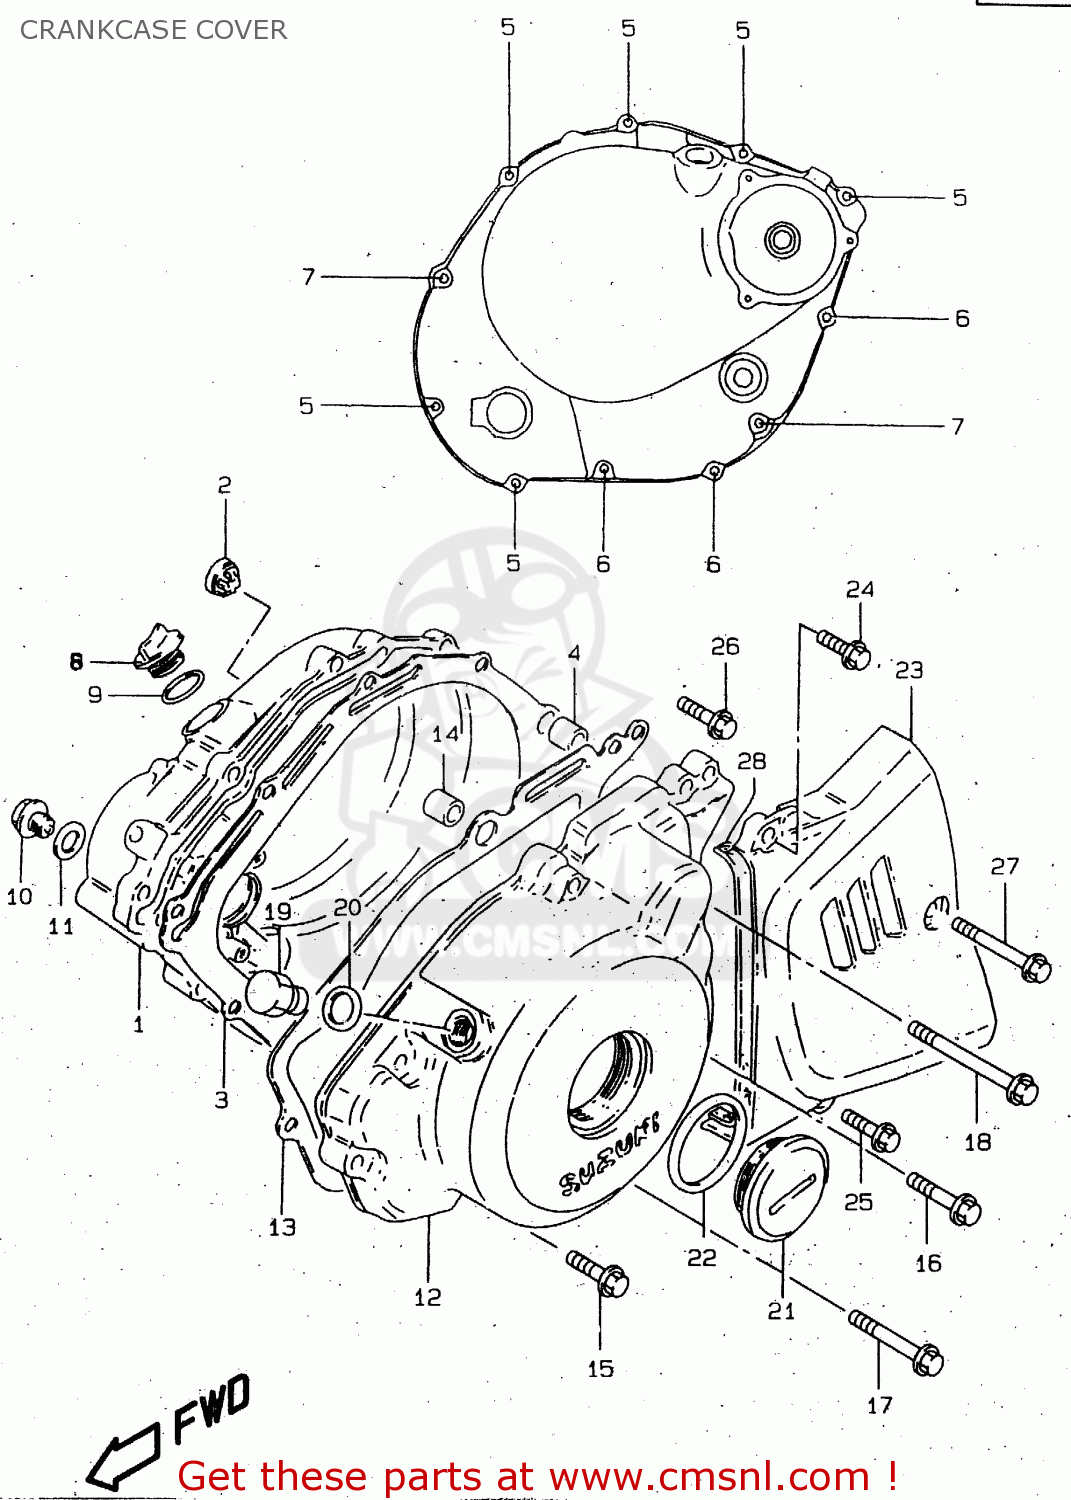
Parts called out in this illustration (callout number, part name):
1	COVER,CLUTCH
2	LENS,OIL LEVEL CHECK
3	GASKET,CLUTCH COVER (NAS)
4	PIN
5	BOLT
6	BOLT
7	BOLT
8	PLUG(20X10)
9	O RING(D:3.1,ID:16.8)
10	PLUG(14X12)
11	GASKET(13.8X18.8X4.8) (NAS)
12	COVER,MAGNETO
13	GASKET,MAGNETO COVER (NAS)
14	PIN
15	BOLT
16	BOLT
17	BOLT
18	BOLT
19	PLUG,12X9
20	GASKET(12.1X16.2X3.7) (NAS)
21	PLUG,36X10
22	O RING(D:3.1,ID:32.7)
23	COVER,ENGINE SPROCKET
24	BOLT
25	BOLT
26	BOLT
27	BOLT
28	DAMPER,ENGINE SPROCKET COVER
